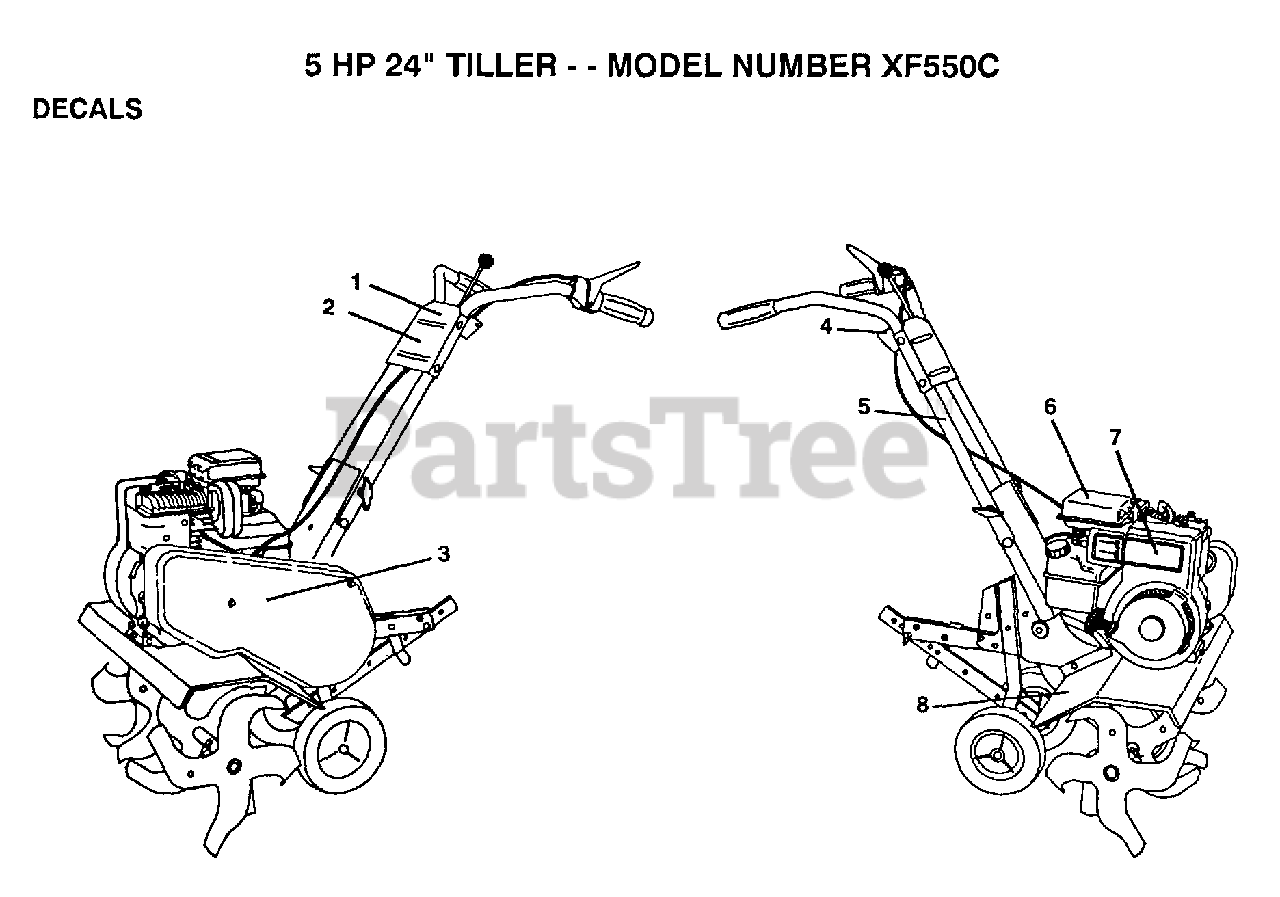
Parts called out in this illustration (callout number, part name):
1	DECAL, LOGO
3	DECAL, LOGO
4	DECAL REVERSE
5	DECAL TI
6	DECAL TI
